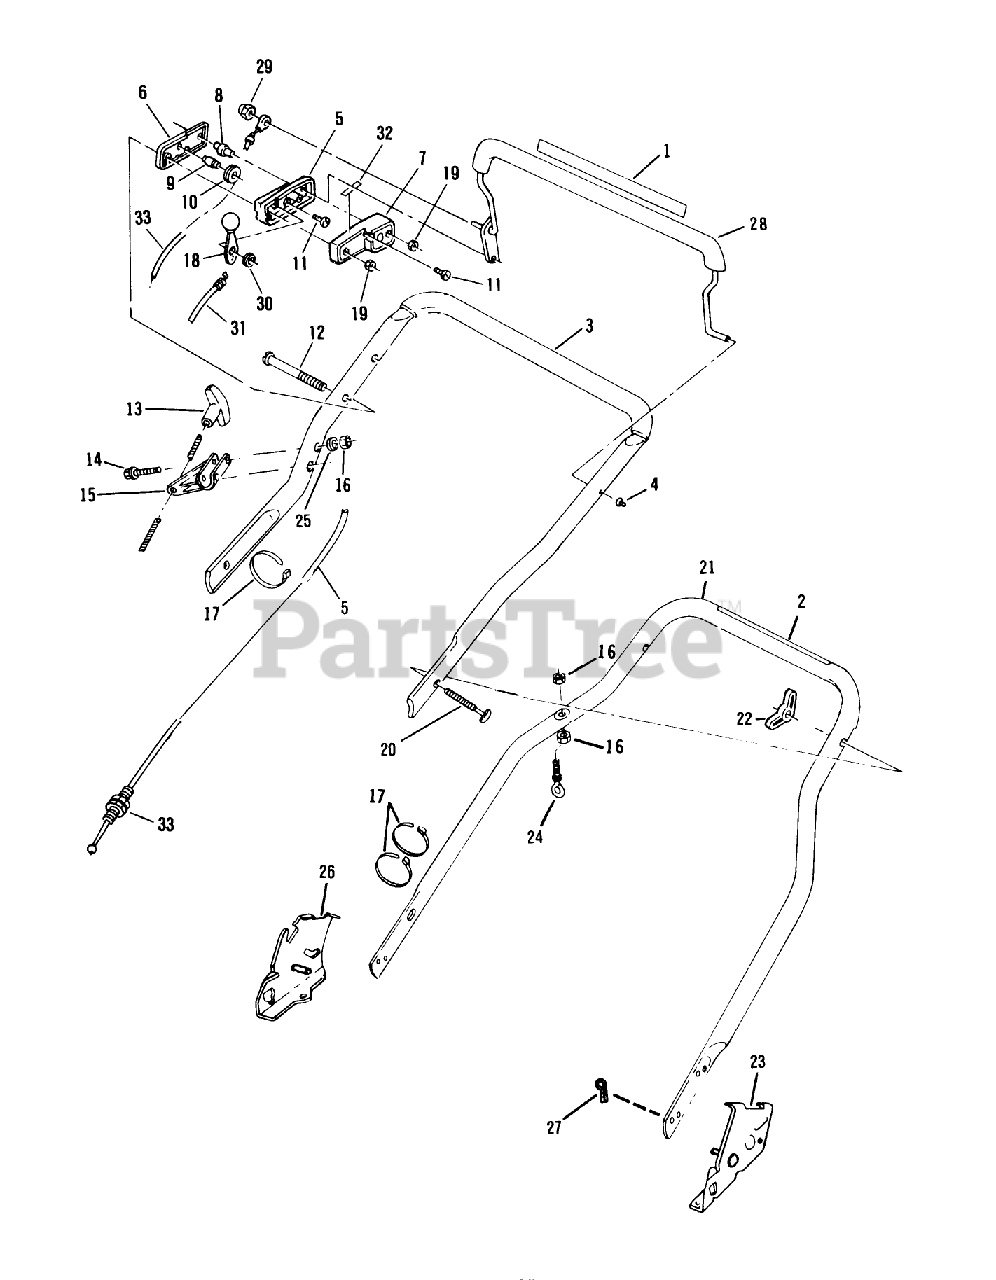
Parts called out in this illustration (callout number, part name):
3	HANDLE-TOP *G
8	COLUMN
9	PIN SKF
10	PULLEY PL
11	SCREW
12	SCREW
13	HANDLE START UM&D
16	LOCKNUT E
18	LEVER&KNOB AY WES
19	NUT C/LOCK E
20	BOLT QUALITY
22	NUT-WING
24	EYE BOLT WAS MFG
25	WASHER
27	HAIR PIN
29	NUT ACORN
30	WASHER-SPRING
31	CABLE THROT WES
33	CONTROL CABLE WES
